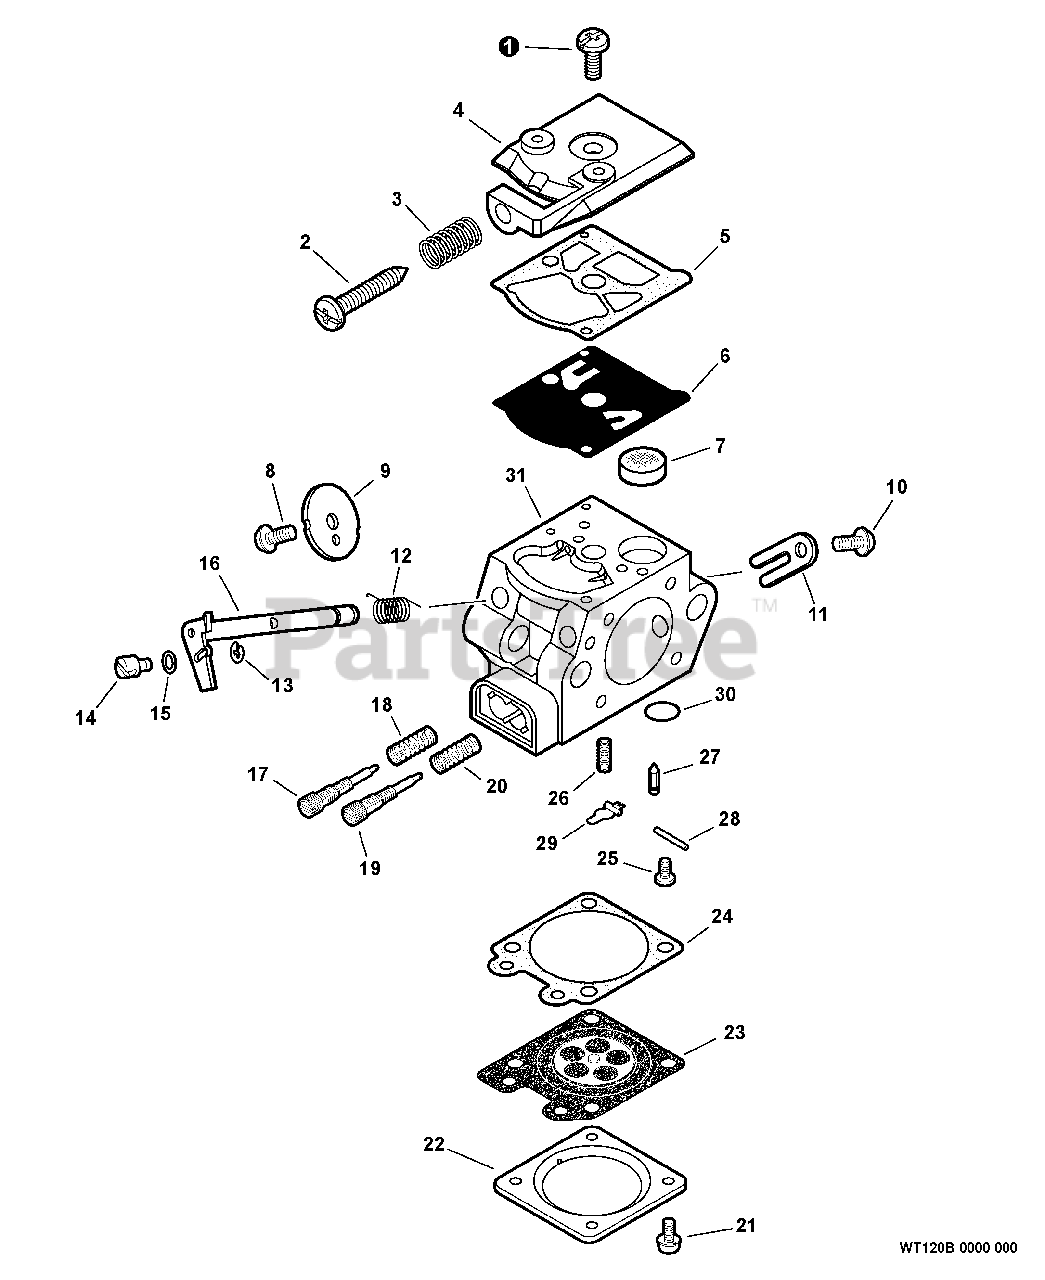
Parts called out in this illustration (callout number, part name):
1	SCREW, PUMP COVER
2	SCREW, IDLE ADJUST
3	SPRING, IDLE ADJUST
4	COVER, PUMP
5	GASKET, PUMP
6	DIAPHRAGM, PUMP
7	STRAINER
9	VALVE, THROTTLE
11	CLIP, THROTTLE SHAFT
12	SPRING, THROTTLE RETURN
13	RING, RETAINING
16	SHAFT, THROTTLE
17	NEEDLE - LOW SPEED
19	NEEDLE - HIGH SPEED
22	COVER, METERING
23	DIAPHRAGM, METERING
24	GASKET, METERING
25	SCREW, METERING LEVER PIN
26	SPRING, METERING LEVER
27	VALVE, INLET NEEDLE
28	PIN, METERING LEVER
29	LEVER, METERING
30	PLUG, WELCH
31	BODY, CARBURETOR
